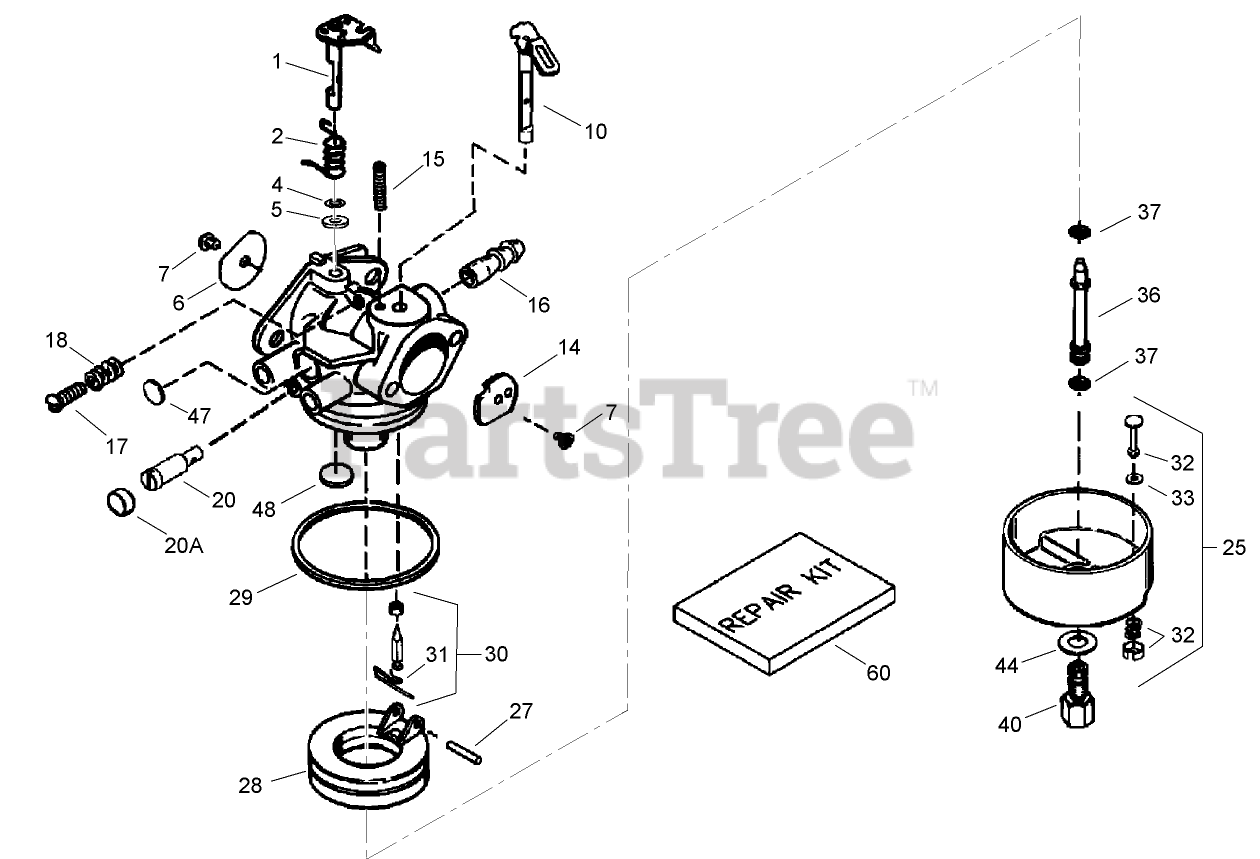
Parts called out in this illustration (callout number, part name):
1	Throttle Shaft and Lever ASM
2	Spring-Return, Throttle
4	Washer-Seal, Dust
5	Seal-Dust
6	Shutter-Throttle
7	Screw-Shutter
10	Choke Shaft and Lever ASM
14	Shutter-Choke
15	Spring-Positioning, Choke
16	Fitting-Fuel
17	Screw-Throttle Crack and Idle Speed
18	Spring-Tension
20	Screw-Restrictor, Idle
20A	Cap-Screw, Idle Restrictor
25	Float Bowl Asm. (Incl. Ref. # 32, 33)
25	Bowl-Float (no drain)
27	Shaft-Float
28	Float (Plastic)
29	O Ring-Bowl, Float
30	Inlet Needle, Seat Clip Assy. (Incl. No. 13)
31	Clip-Spring
32	Bowl Drain ASM
33	Gasket-Plunger, Drain
36	Tube-Nozzle, Main
37	O-Ring
40	Nut-Bowl, High Speed
44	Washer-Nut, Bowl
47	Plug-Welch, Idle Mixture Well
48	Plug-Welch, Atmospheric Vent
60	Repair Kit
